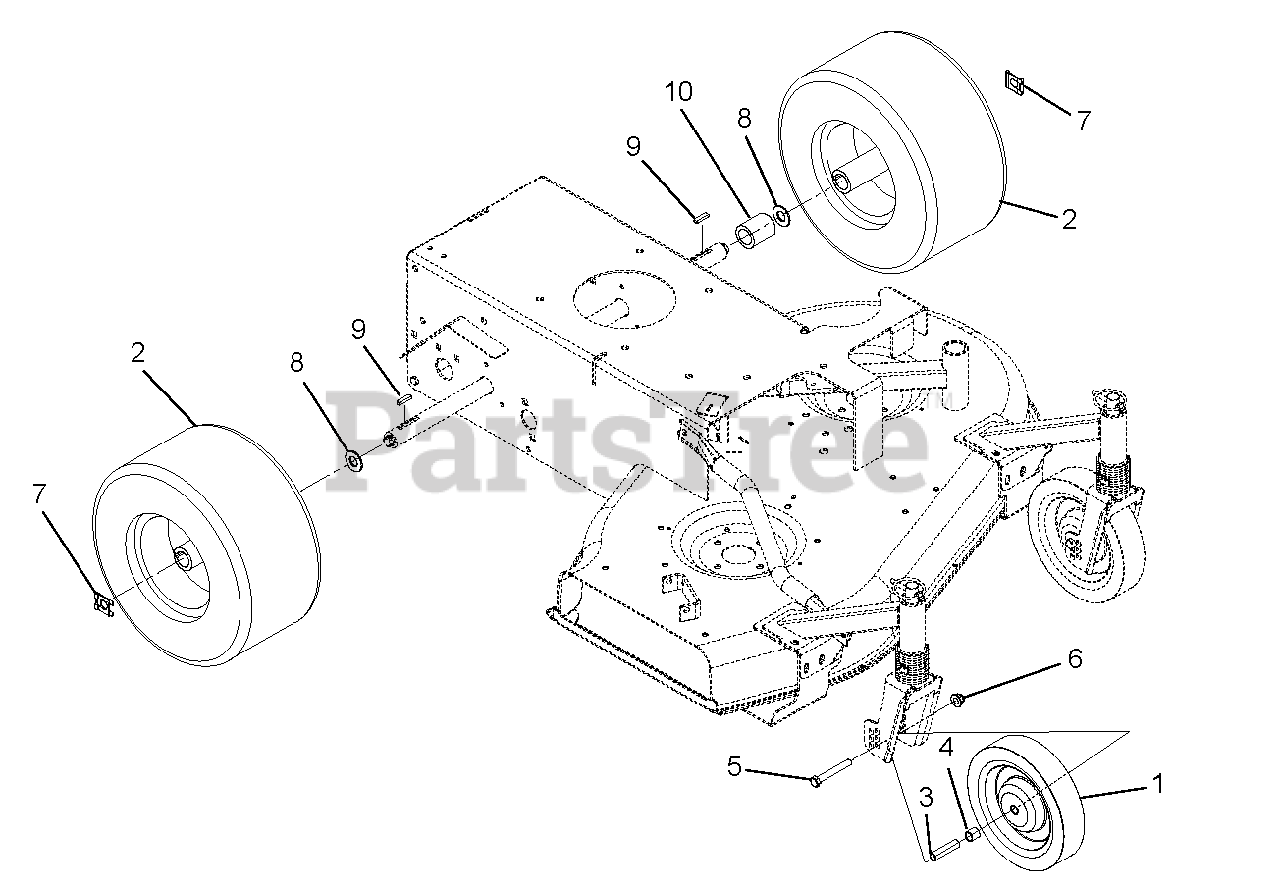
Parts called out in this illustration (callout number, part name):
1	Wheel, 8.0 x 1.75 x .50 Ball Bearing
2	Assembly, Tire/Wheel 6 x 13
3	Spacer, Wheel
4	Spacer, Wheel
5	Bolt, Hex .38-16 x 2.75
6	Nut, Nyloc Flange .38-16
7	Clip, Snap .625 Diameter
8	Washer, Flat Steel .656 x 1.31 x .095
9	Key, Rectifier .25 x .188 x 1.00
10	Spacer 1.0 x 1.5 x 1.57
